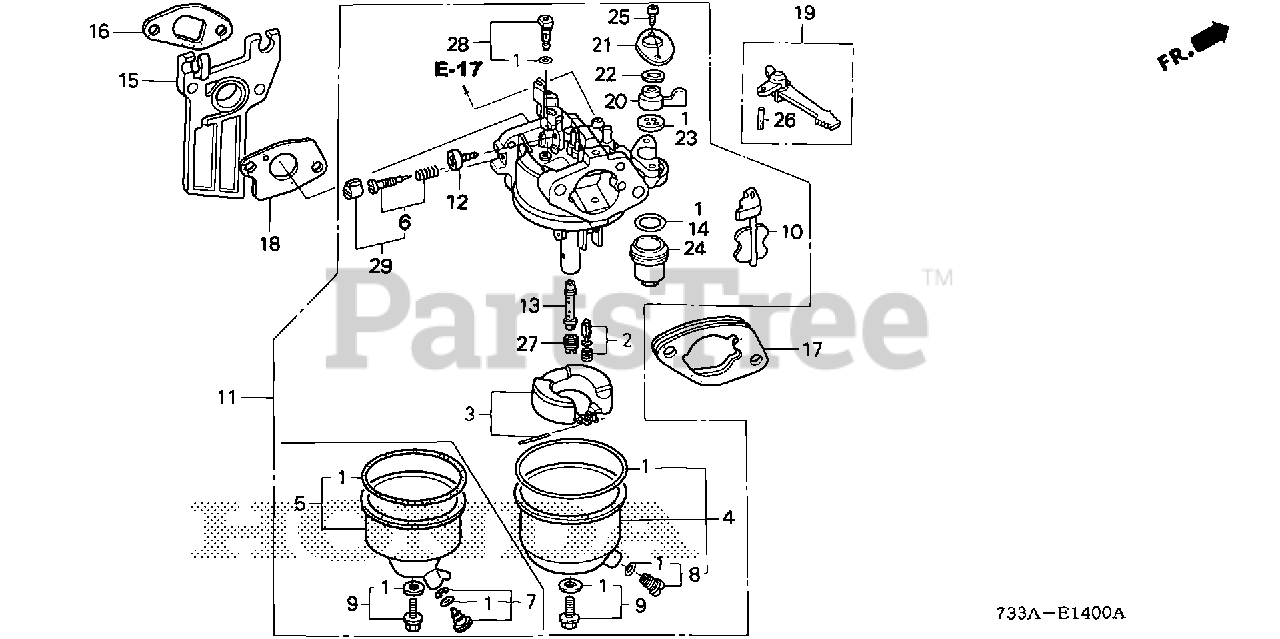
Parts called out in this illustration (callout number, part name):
1	GASKET SET (CARBURETOR NO.)
2	VALVE SET, FLOAT (SEAT NOT INCLUDED)
4	CHAMBER SET, FLOAT
6	SCREW SET, PILOT (CARBURETOR NO.)
8	SCREW SET, DRAIN (CARBURETOR NO.)
9	SCREW SET
10	CHOKE SET (NOT AVAILABLE)
11	CARBURETOR ASSY. (BE01E F)
11	CARBURETOR ASSY. (BE01E G)
12	SCREW, THROTTLE STOP
13	NOZZLE, MAIN (NOT AVAILABLE)
14	GASKET, FUEL STRAINER CUP
15	INSULATOR, CARBURETOR
16	GASKET, INSULATOR
17	SPACER, CARBURETOR
18	GASKET, CARBURETOR
19	LEVER, CHOKE (STD)
20	LEVER, VALVE
20	LEVER, PETCOCK (CARBURETOR NO.)
21	PLATE, LEVER SETTING (CARBURETOR NO.)
22	SPRING, PETCOCK LEVER (CARBURETOR NO.)
23	GASKET, PETCOCK (CARBURETOR NO.)
24	CUP, FUEL STRAINER
25	SCREW, PAN (3X8) (CARBURETOR NO.)
26	PIN, SPRING (2X12)
27	JET, MAIN (#62)
27	JET, MAIN (#65)
27	JET, MAIN (#68)
28	JET SET, PILOT (#35)
